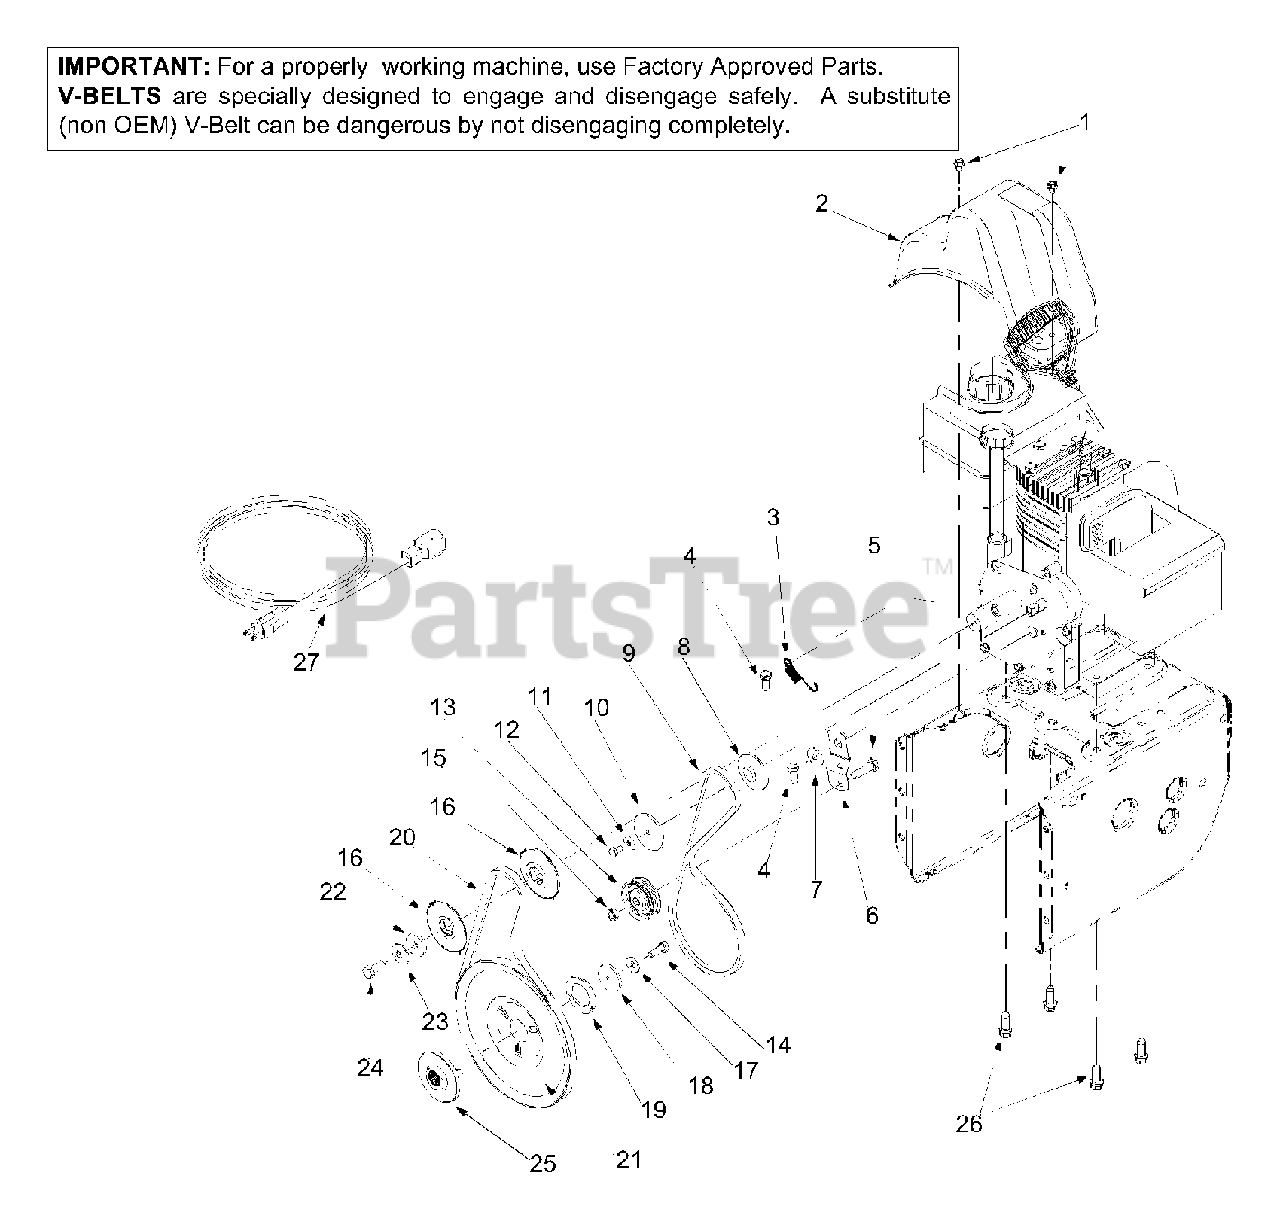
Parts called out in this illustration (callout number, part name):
1	Hex Washer Screw 1/4-20 x.5
2	Belt Cover
3	Extension Spring
4	Hex Screw 5/16-24 x .75
5	Hex Cap Screw 3/8-16 x 1.25
8	Pulley Half
9	V-Belt
10	Pulley Half
11	Bell Washer
12	Hex Cap Screw 1/4-28 x .50
13	Flat Idler
14	Lock Cap Screw 5/16-24
15	Lock Jam Nut 3/8-16
16	Pulley Half
17	Bell Washer
18	Flat Washer
19	Washer
20	Belt
21	Auger Pulley
22	Flat Washer
23	Bell Washer
24	Hex Cap Screw 3/8-24
25	Pulley
26	Hex Washer Screw 3/8-16 x 1.0
27	Extension Cord
